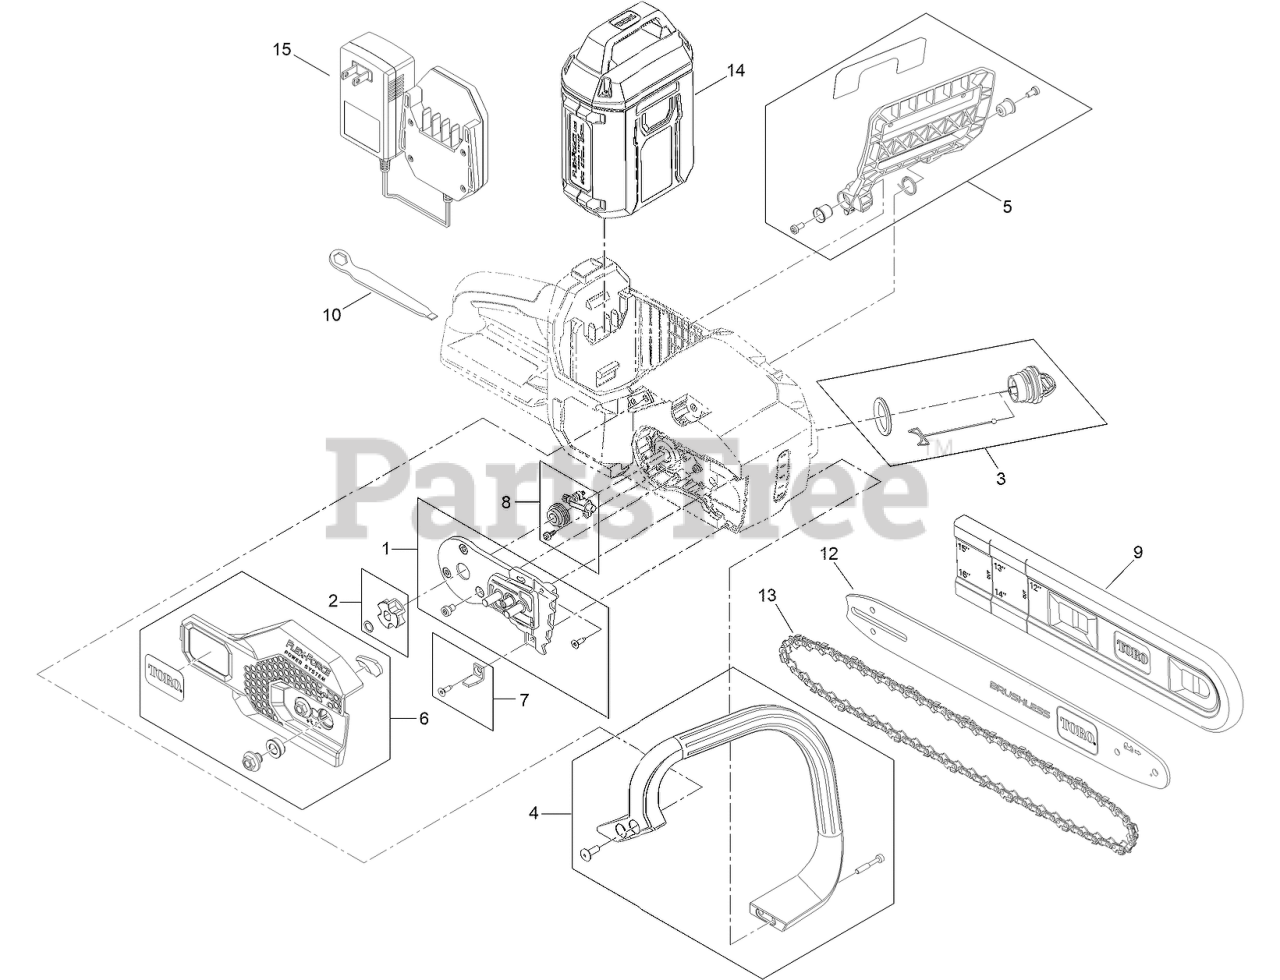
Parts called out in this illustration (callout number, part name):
1	ADJUSTER BAR BRACKET ASM
2	DRIVE GEAR ASM
3	OIL CAP ASM
4	HANDLE ASM
5	CHAIN BRAKE ASM
6	BAR COVER ASM
7	BAR COVER SUPPORT BRACKET ASM
8	OIL PUMP ASM
9	BAR-SLEEVE, CHAINSAW
10	TOOL-ADJUSTMENT, BAR
12	BAR-REPLACEMENT
13	CHAIN
14	BATTERY-60V 2.0AH
15	CHARGER-BATTERY, 60V 1 AMP
